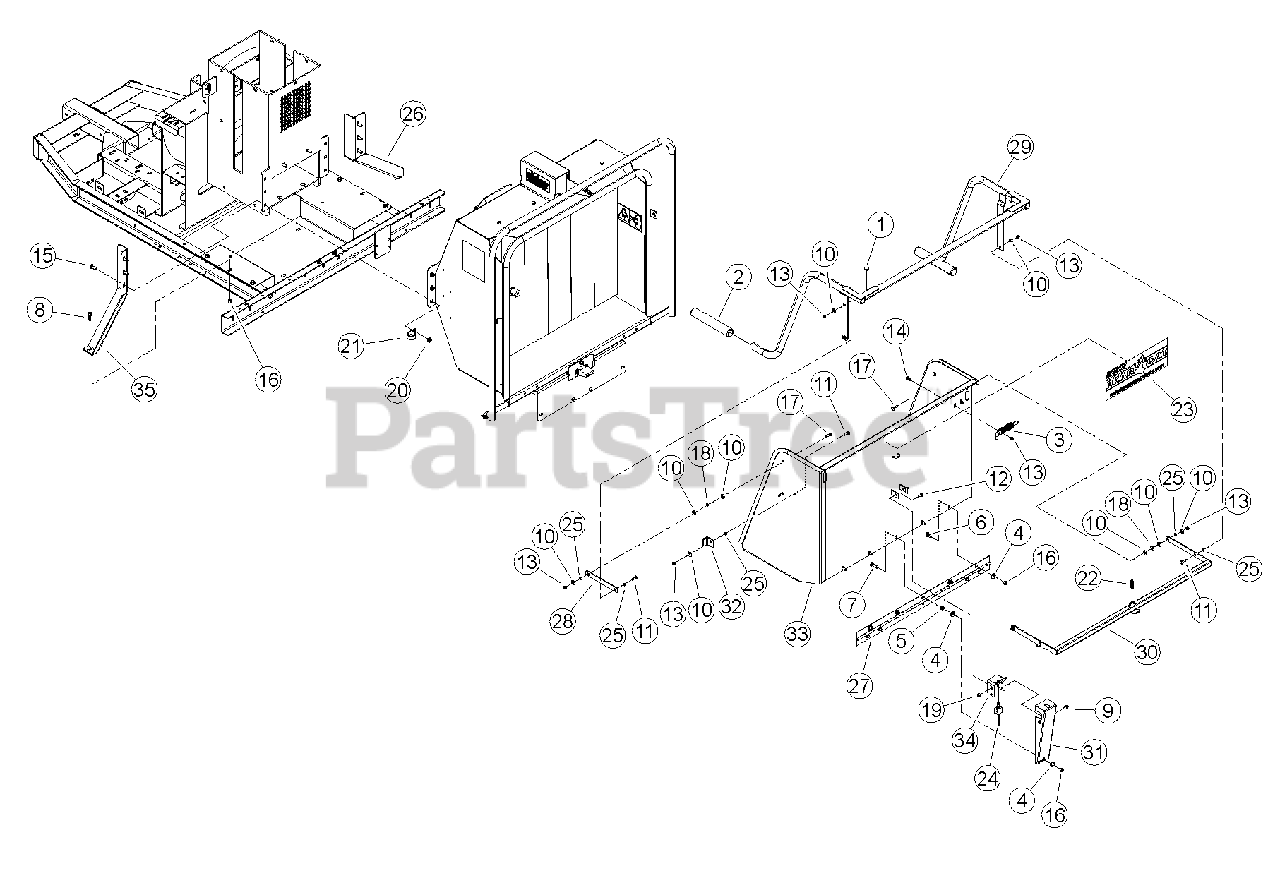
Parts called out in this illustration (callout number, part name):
1	BUMPER, RUBBER
2	GRIP, 1.219 X 10.00
3	LATCH, RH HINGE
4	WASHER, 3/8" FLAT ZP
5	NUT, 3/8" SERRATED FLANGE NC ZP
6	BOLT, 3/8 X 1" GR5 CRG NC ZP
7	BOLT, 3/8 X 1-1/2" GR5 CRG NC ZP
8	BOLT, 3/8 X 1-1/4 FLANGE NC
9	SCREW, 11/32 X 7/8 HWH AB THREAD ZP
10	WASHER, 5/16" FLAT ZP
11	BOLT, 5/16 X 1" GR5 CRG ZP
12	BOLT, 5/16 X 7/8" GR5 CRG NC ZP
13	NUT, 5/16" NE NYLOCK ZP
14	BOLT, 5/16 X 3/4 GR5 CRG NC ZP
15	BOLT, 3/8 X 1-1/4" GR5 CRG NC ZP
16	NUT, 3/8" NE NYLOCK ZP
17	BOLT, 5/16 X 1-1/4" GR5 CRG ZP
18	WASHER, 5/16" ID 7/8" OD NYLON FLAT
19	NUT, 5/16-18 NYLOCK-FLANGE
20	NUT, 3/8-16 NYLOCK FLANGE
21	CLAMP, 1 9/16 COATED METAL
22	SPRING 1/2 X 2.00 LG,ZP
23	DECAL, BEARCAT WEB
24	SWITCH, MOMENTARY IP67 NORMALLY ON
25	SPACER, IDLER PIVOT
26	BRACKET, CHUTE SUPPORT RH
27	HINGE, EXTENSION TRAY
28	LINK, PARALLEL
29	WELDMENT, KNEEBAR
30	WELDMENT, KNEEBAR PIVOT
31	SHIELD, KNEEBAR SWITCH
32	LOCK, SAFETY BAR
33	WELDMENT, EXTENSION TRAY
34	BRACKET, SWITCH
35	WELD, PLATE LH SUPPORT
